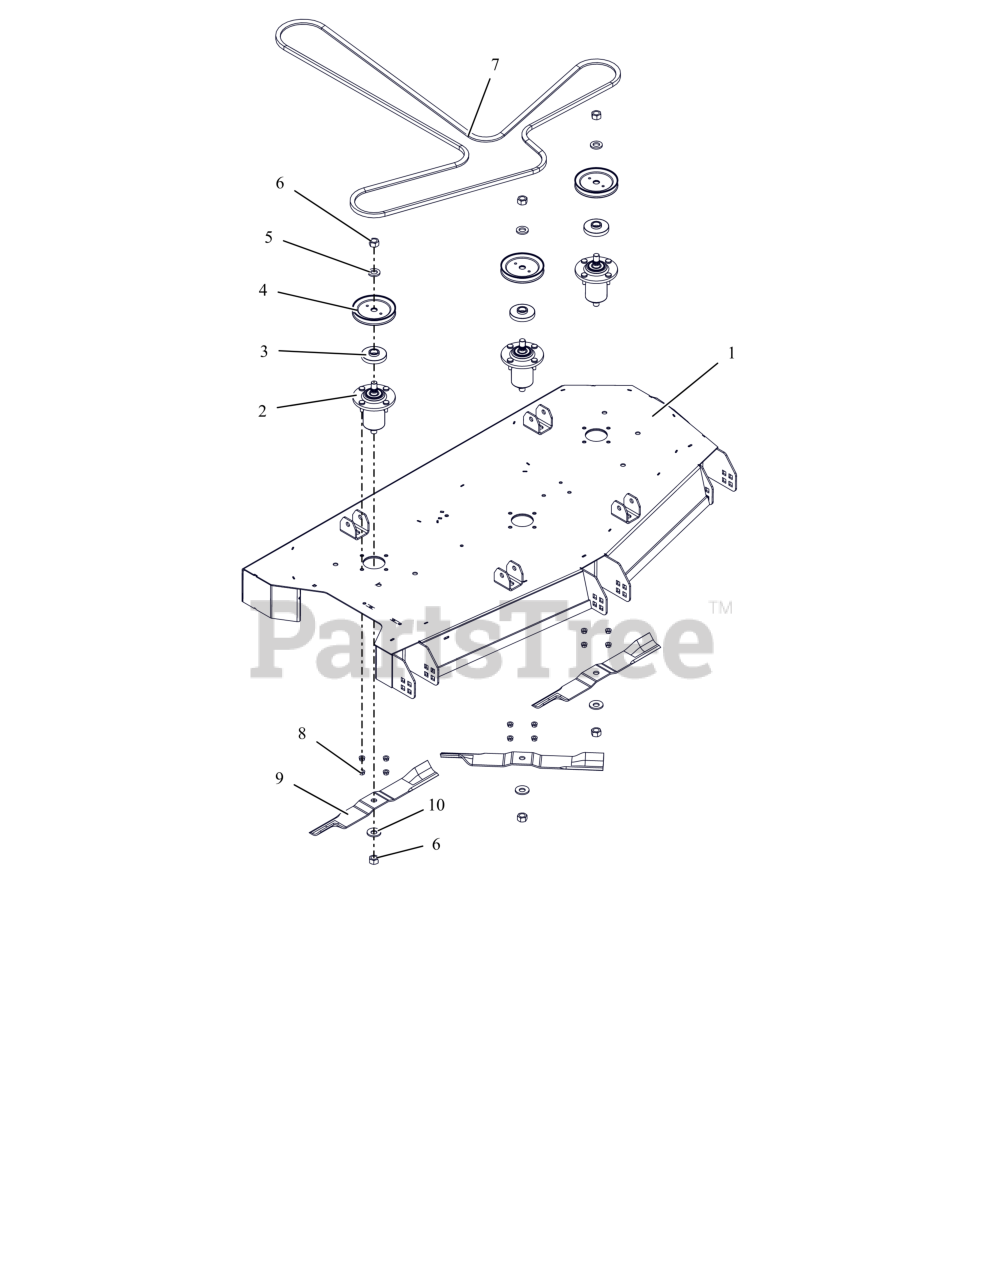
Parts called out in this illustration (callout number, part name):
1	KIT-GRAVELY DECK 52" W/ DECALS
2	ASM, ALUMINUM SPINDLE SUB
3	SHIELD, DUST
4	PULLEY-V-4.75 ODX.625SPLINE ID
5	SPCR- .735 X 1.313 X .165
6	NUT-STD .625-18 ZCC
8	NUT,LK-CTR-FLG .31-18 GF ZCC
9	BLADE- 18.0" MOWER (HI-LIFT)
10	WSHR-BLVL .669X1.535X.138
